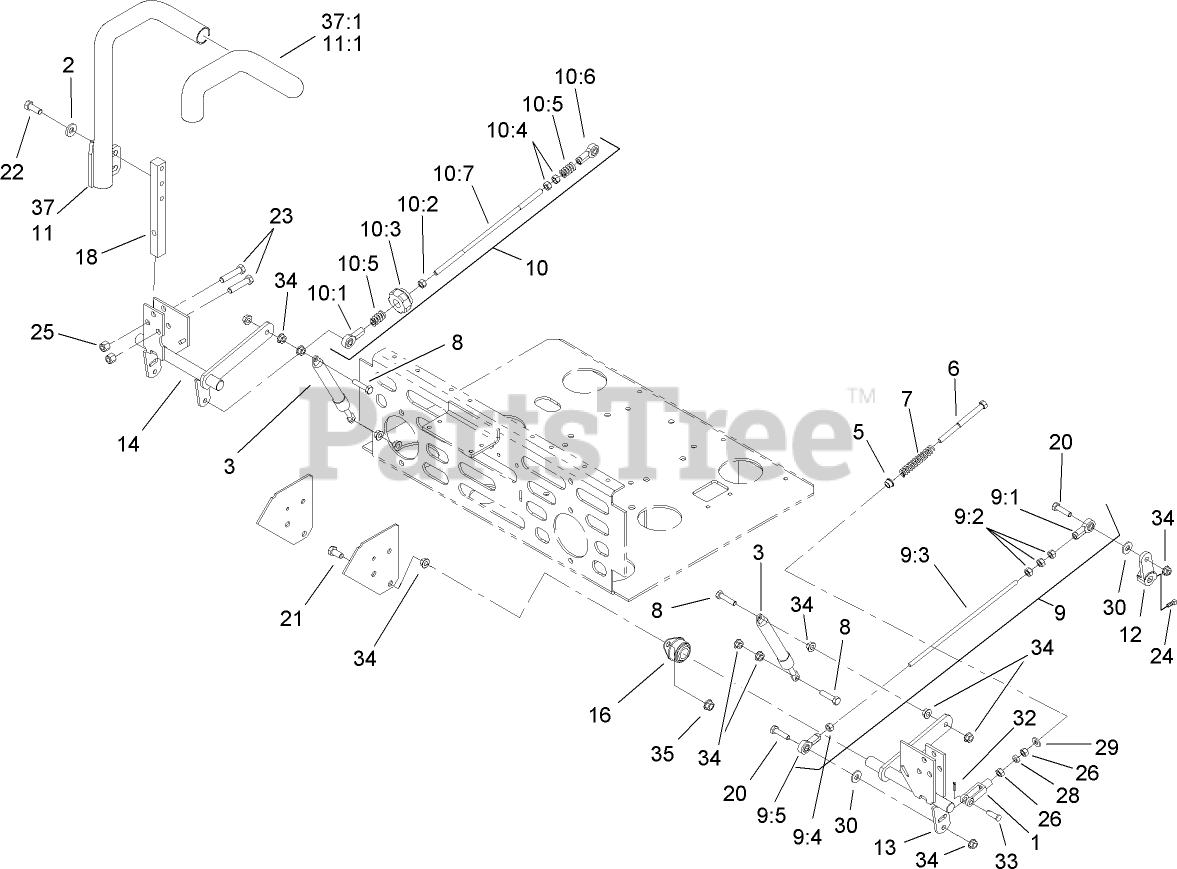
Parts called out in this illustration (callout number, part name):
1	YOKE-ADJUSTABLE
2	WASHER-BELLEVILLE
3	DAMPER-CONTROL, MOTION
5	BUSHING-FLANGED
6	BOLT-RETURN, NEUTRAL
7	SPRING-RETURN, NEUTRAL
8	SCREW-HH
9	Tracking Rod ASM
9:1	BALLJOINT-RH
9:2	NUT-HEX
9:3	Link-Rod, Tracking
9:5	BALLJOINT-LH
10	Tracking Rod ASM
10:1	BALLJOINT-RH
10:2	NUT-HEX
10:3	KNOB-TRACKING
10:5	SPRING-COMPRESSION
10:6	BALLJOINT-LH
10:7	Link-Rod, Tracking
11	LH LEVER ASM
12	ARM-CONTROL, PUMP
13	Control-Motion, LH
14	Control-Motion, RH
16	BEARING-FLANGE, SIDE
18	ARM-SHAFT, CONTROL
20	SCREW-HH
21	SCREW-HH
22	SCREW-HH
23	SCREW-HH
24	SCREW-SET
25	NUT-LOCK, NI
26	NUT-HEX
28	NUT-JAM
29	WASHER-FLAT
30	WASHER-FLAT
32	PIN-COTTER
33	PIN-CLEVIS
34	NUT-HF
35	NUT-HHF, WHIZ
37	RH LEVER ASM
37:1	GRIP-CONTROL, MOTION
